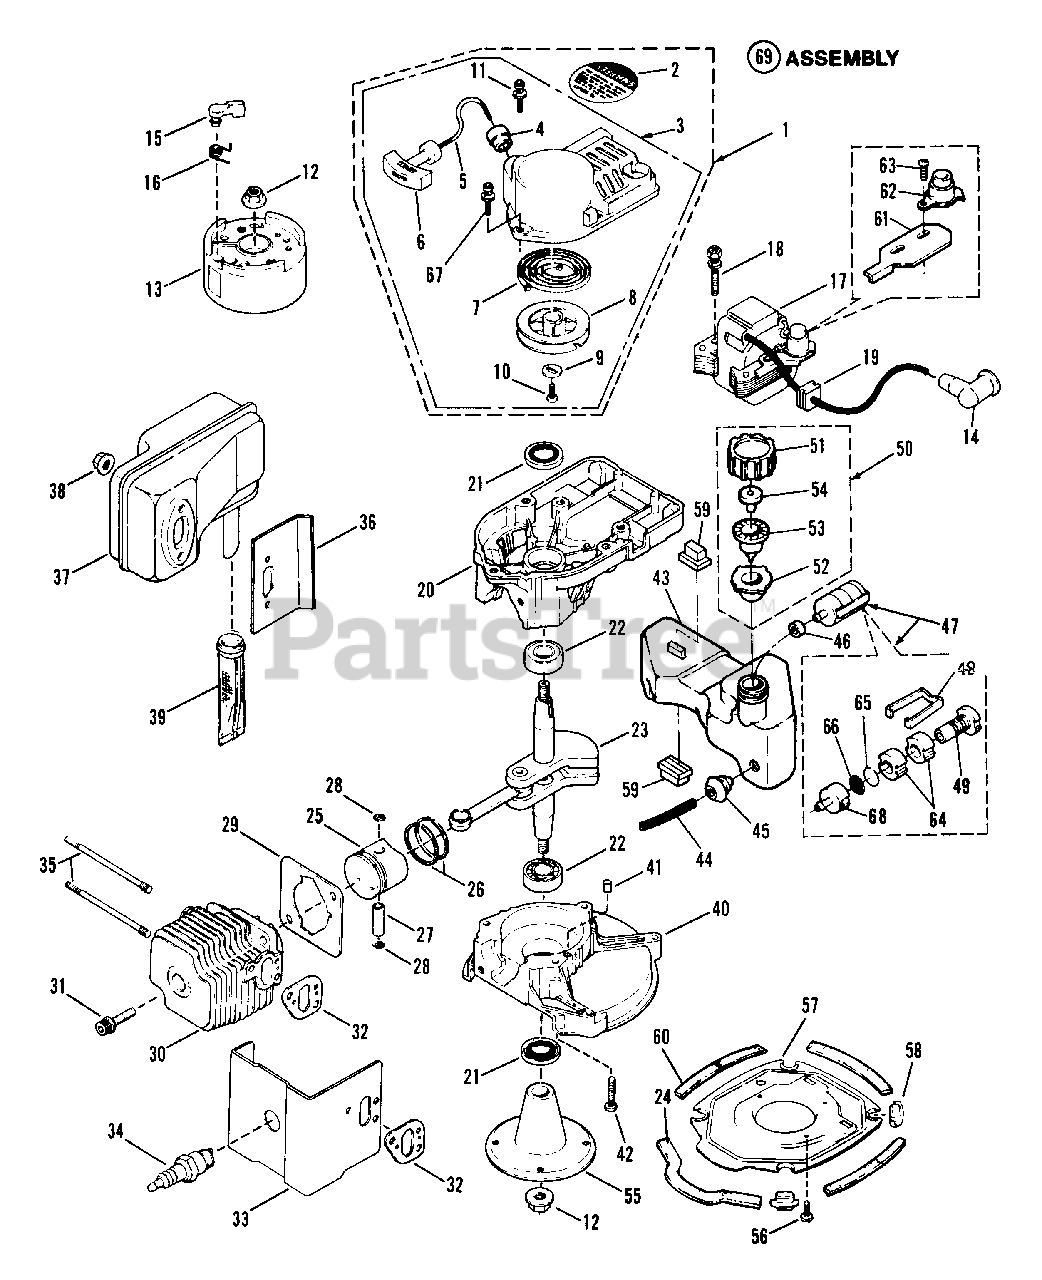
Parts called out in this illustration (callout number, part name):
1	RECOIL STARTER ASS'Y W/LABEL
2	LABEL,Starting instruction
3	RECOIL STARTER ASS'Y
4	ROPE GUIDE
5	ROPE, Starter
6	KNOB, Starter
7	SPRING, Recoil
11	SCREW & WASHER
12	NUT, Conical
14	CAP, Plug
15	PAWL, Starter
16	SPRING, Pawl
17	COIL,lgnition
19	GROMMET
20	CASE, Starter
21	SEAL, Oil
22	BEARING, Ball
23	CRANKSHAFT ASS'Y.
24	SEAL, Engine Plate, Front
25	PISTON
26	RING, Piston
27	PIN, Piston
28	CLIP, Piston Pin
29	GASKET, Cylinder
30	CYLINDER
31	BOLT, Flange
32	GASKET, Carburetor Mounting
33	SHIELD, Carburetor
35	STUD, Muffler
36	SHIELD, Muffler
37	MUFFLER
38	NUT, Muffler Stud
39	SPARK ARRESTOR
40	CASE, Drive
41	PIN, Dowel
42	SCREW, M5 x 25mm
43	FUEL TANK ASS'Y.
44	LINE, Fuel
45	GROMMET, Fuel Line
46	CLIP, Fuel Line
47	FILTER ASS'Y, Fuel
49	SLEEVE, Gov
50	CAP ASS'Y,
51	CAP, Fuel
52	GASKET
54	VALVE, Breather
55	MOUNT, Fan-Wheel
56	SCREW, M5x12mm PHCR
57	MOUNTING PLATE, Engine
58	DAMPER,Eng.Mtg Plate
59	PAD, Fuel Tank
60	SEAL, Eng. Mtg. Plate
61	BRACKET
62	SWITCH, Stop
68	BODY, Fuel Filter
69	ENGINE, COMPLETE
